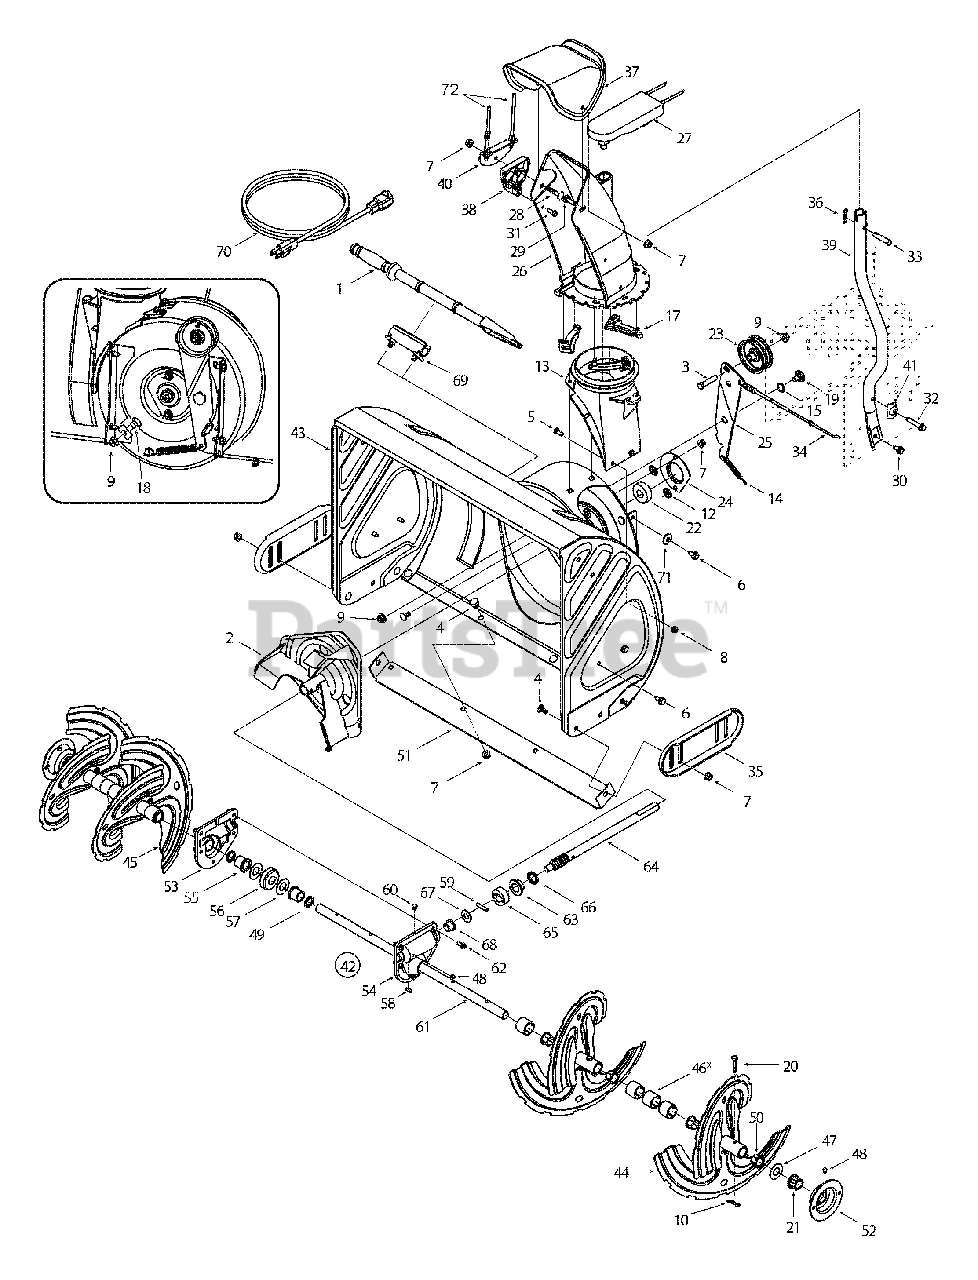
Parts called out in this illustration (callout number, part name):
1	Removal Tool, Snow
3	Screw, 3/8-16 x 1.75, Gr. 5, Std
4	Bolt, Carriage, 5/16-18 x.750 Gr. 1
5	Screw, Carriage, 1/4-20 x .75, Gr5
6	Screw, 5/16-12 x 0.750
7	Nut, Flange Lock, Nylon, 5/16-18, Gr F
8	Nut, Flange Lock, Nylon, 1/4-20, Gr F
9	Nut, Flange Lock, Nylon, 3/8-16, Gr F
10	Pin, Cotter, 3/32 x .750
11	Cable, Tie, 3/16 x .05 x 7.4
12	Nut, Push-on, .25 Dia
13	Chute, Adapter 5" Dia
14	Spring, Extension, .38 OD x 3.6
15	Washer, Wave, .625 x .885 x .015
16	Washer, Flat, .25 x .630 x .0515
17	Keeper, Flange
18	Screw, Shoulder, .498 x .340, 3/8-16
19	Screw, Shoulder, .625 x .17, 3/8-16
20	Pin, Shear, .25 x 1.50, Gr2
21	Bearing, Hex Flange x .75 ID
22	Bearing, Ball, .75 ID x 1.85 OD
23	Pulley, Idler, Flat 2.75 OD
24	Housing, Bearing, 1.85 ID
25	Bracket, Auger Idler w/ Brake
26	Chute Assembly, Lower, 4-way
27	Kit, Rotation Pulley
28	Bolt, Carriage, 5/16-18, 1.50, Gr2
29	Bolt, Carriage, 5/16-18, 1.00
30	Screw, 5/16-12 x 0.75
31	Screw, 1/4-15 x 0.75
32	Screw, Self-tapping 5/16-18 x 1.75
33	Pin, Clevis, 3/8 x 1.75
34	Auger Clutch Cable , 44.75"
36	Pin, Cotter, .072 Dia. x 1.13
37	Upper Chute, Remote
38	Cable Guide, Chute Tilt
41	Tab, Handle
42	Gearbox Assembly, Auger, 26" w/ Fitting
46	Spacer, 1.25 OD x .75 ID x 1.00
47	Washer, Flat, .76 x 1.49 x .06
48	Lube Fitting, 3/16
49	Seal, Oil, .750 ID
50	Bushing, Flange, .800 ID x .910 OD
54	Housing Assembly, Auger, LH Reducer
55	Bearing, Flange, .75 ID x 1.00 OD x .975
56	Gear, Worm 20T
57	Washer, Flat, .760 ID x 1.5 OD
58	Key, Hi-pro 3/16 x 5/8
59	Pin, Dowel, .25 OD x 1.2
60	Plug, 1/4 x .437
61	Axle, Auger, 26"
62	Screw, Self-tapping, 1/4-20, 0.750
63	Bearing, Flange, .75 ID x 1.00 OD x .59
64	Shaft , Worm .75 OD
65	Collar, Thrust
66	Seal, Oil, .75 x 1 x .131
67	Washer, Flat, .5 1 x 1.12
68	Bearing, Flange, .75 ID x 1.00 OD x .925
69	Mount, Clean Out Tool
70	Extension Cord, 3-Prong
71	Washer, Bell, .3 40 x 872 x .060
72	Cable - Chute Deflector
